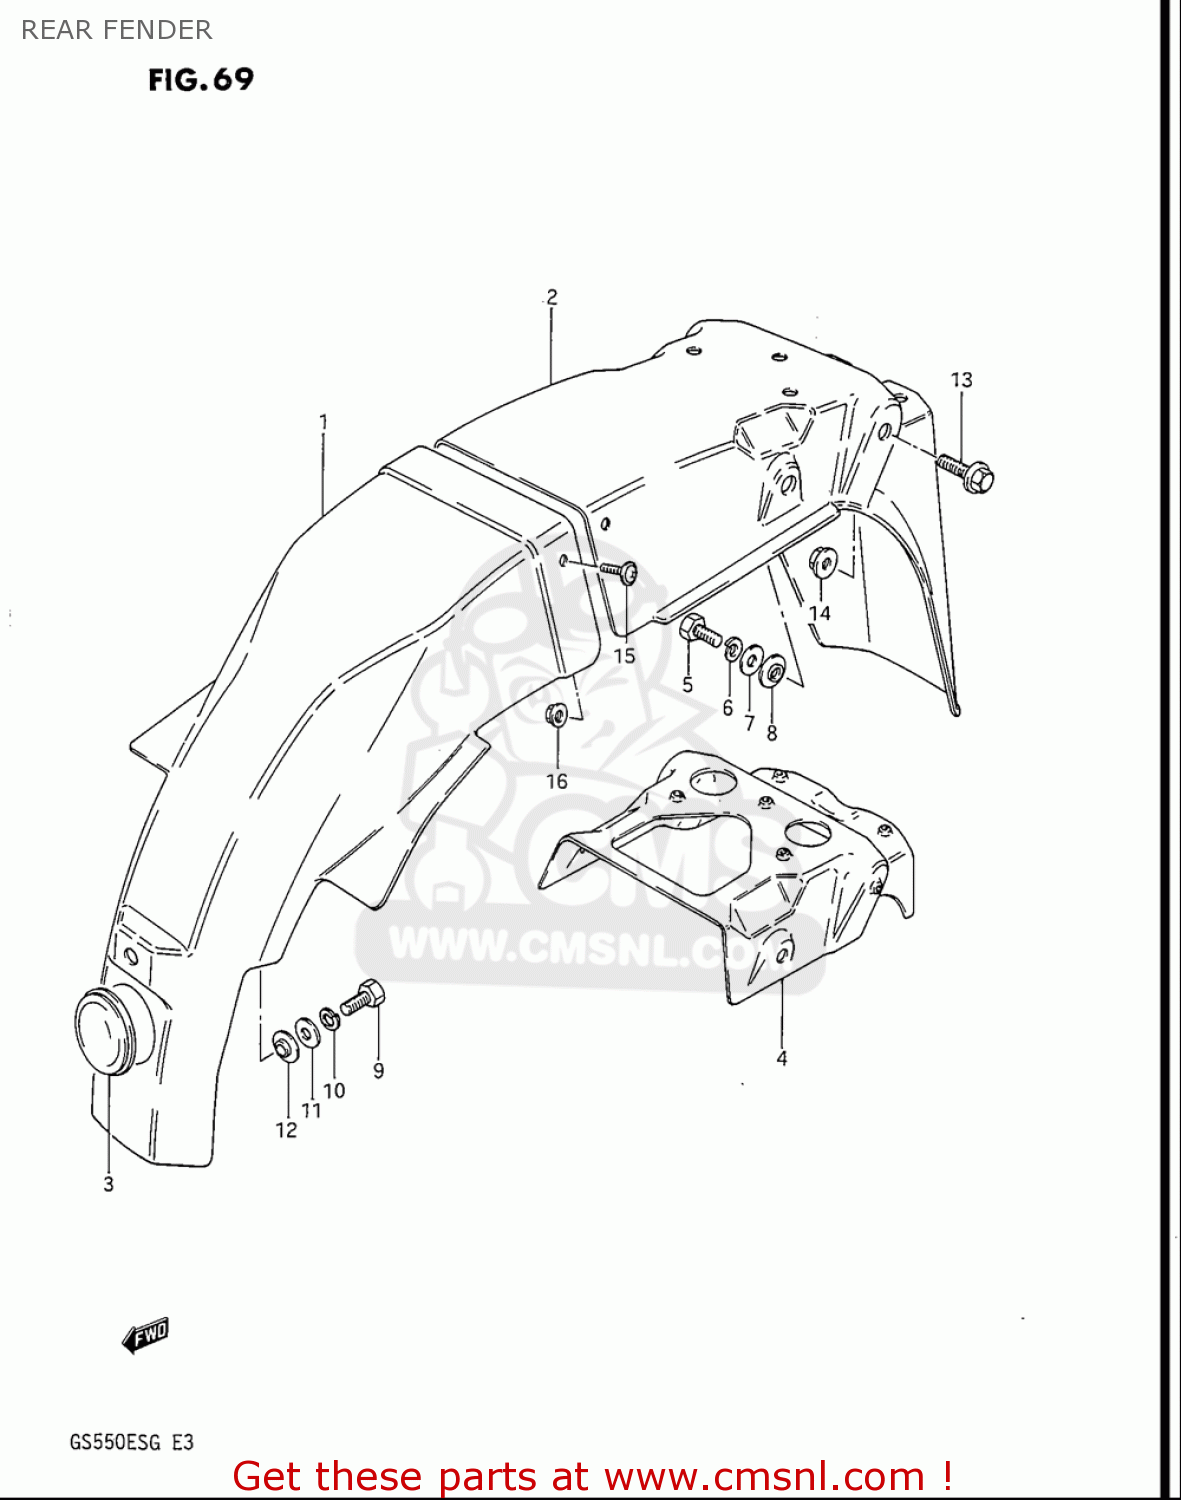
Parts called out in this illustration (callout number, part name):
2	BODY,RR FENDER RR
5	BOLT
6	WASHER,LOCK
7	WASHER
8	WASHER(6.5X18X1.6)
9	BOLT
10	WASHER,LOCK
11	WASHER
12	WASHER
13	BOLT
14	NUT
15	SCREW
16	NUT
